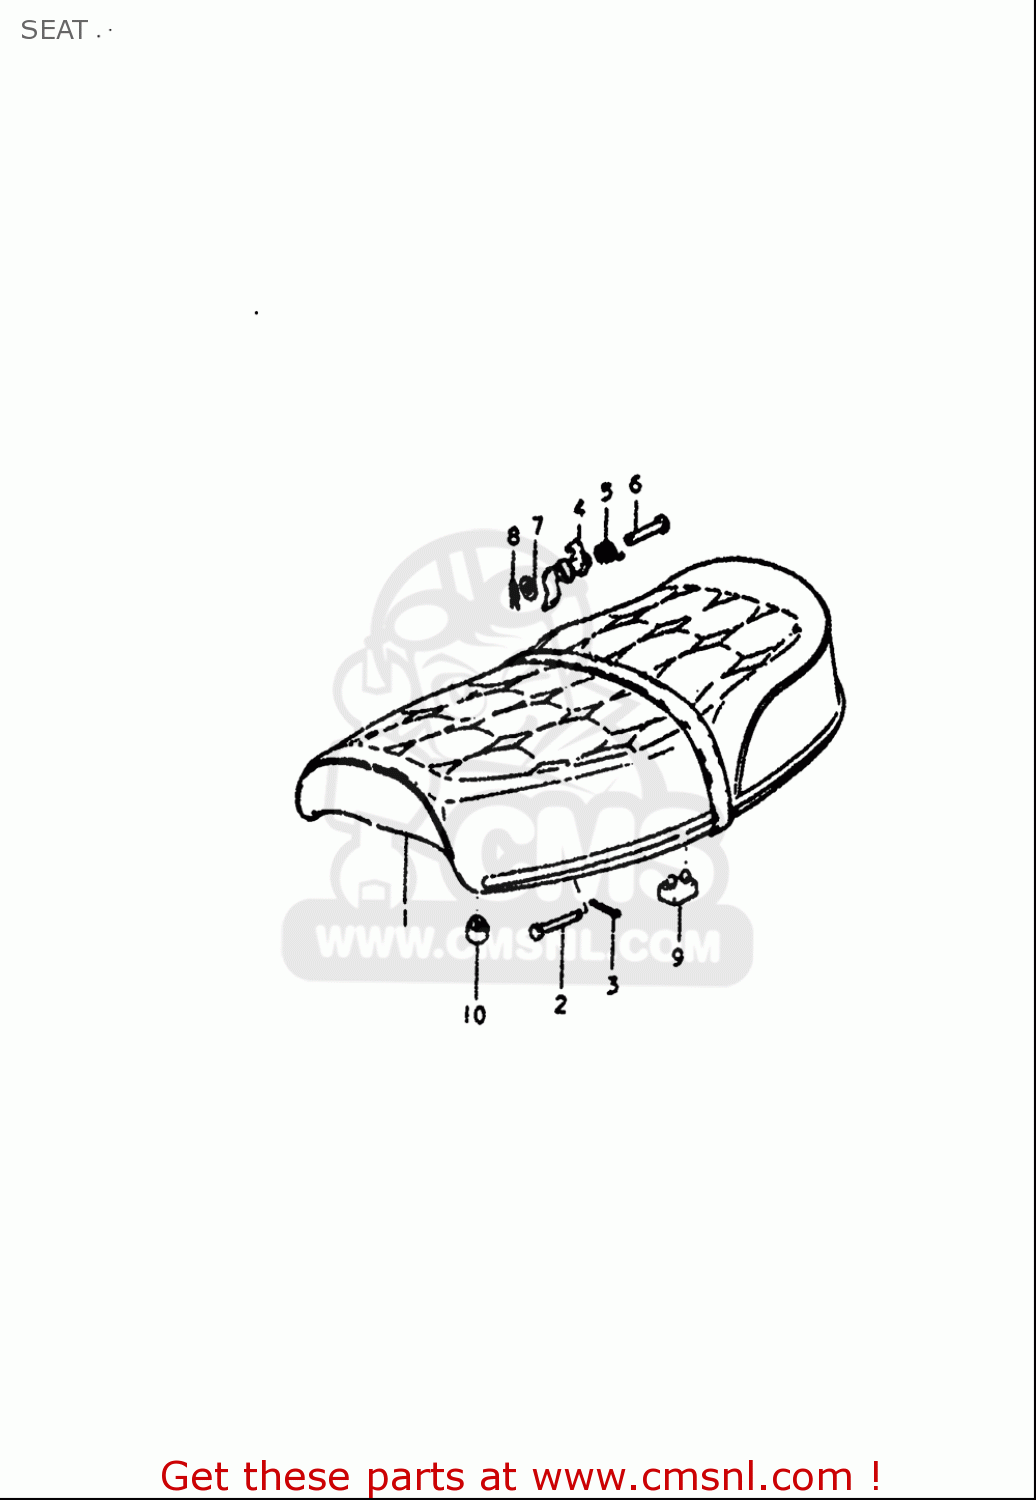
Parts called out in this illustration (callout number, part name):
1	SEAT ASSY
2	PIN
3	PIN
5	SPRING
6	PIN
7	WASHER
9	CUSHION
10	CUSHION
